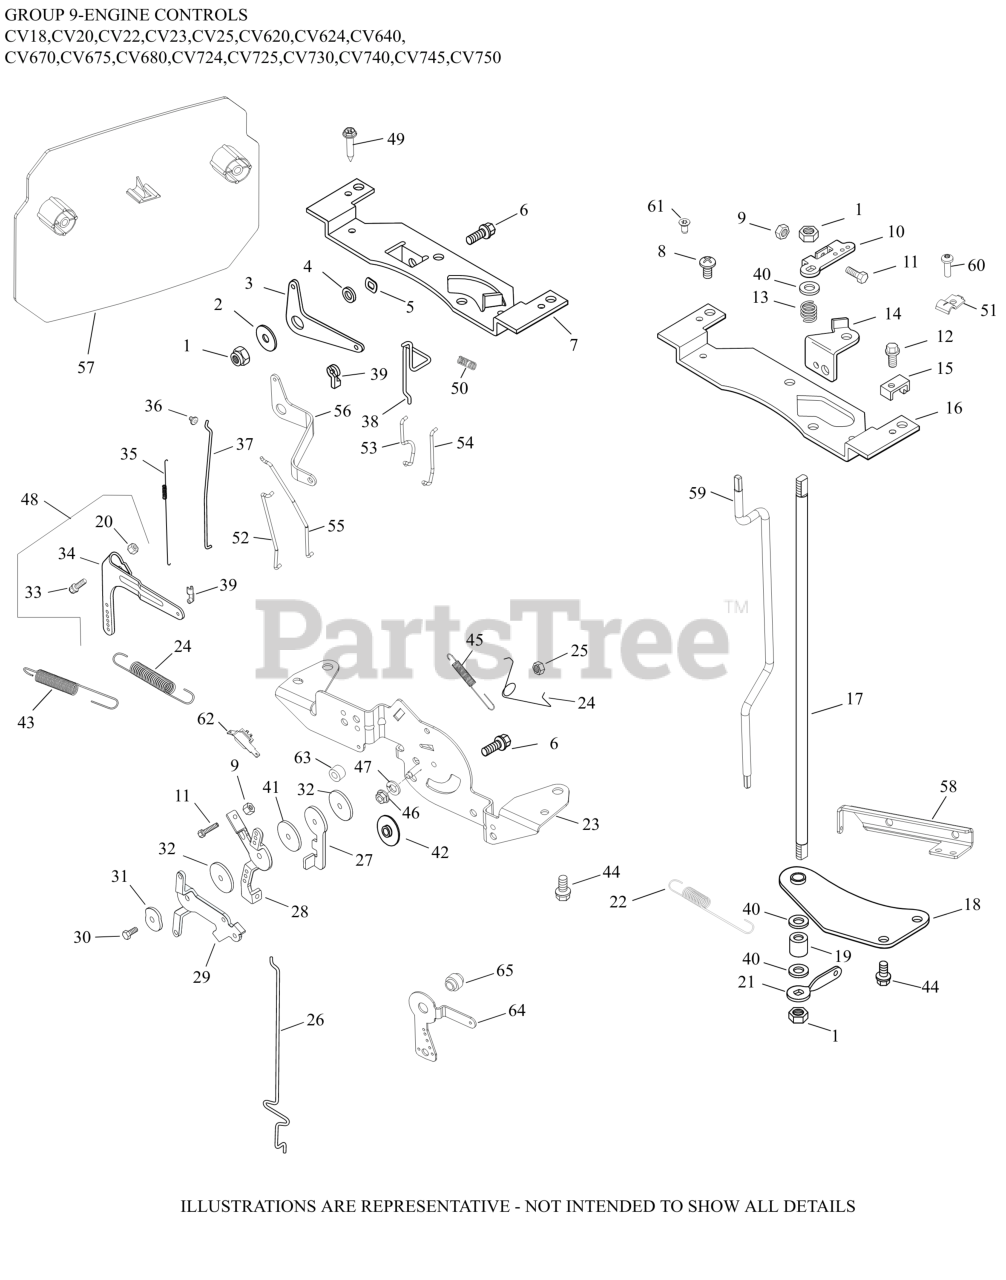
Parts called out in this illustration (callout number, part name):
1	NUT, LOCK M6X1.0
2	WASHER, FLAT 1/4"
3	LEVER, CHOKE
5	WASHER, SPRING 3/8"
6	SCREW, FLG M6X1.0X16
7	BRACKET, CONTROL
9	NUT, M4X0.7
10	LEVER, THROTTLE CONTROL
11	SCREW, CAP M4X.7X30
12	SCREW, HI-LOW
13	SPRING, THROTTLE SHAFT
17	SHAFT, THROTTLE
18	BRACKET, THROTTLE SHAFT
20	NUT, FLG M6X1.0
21	LEVER, THROTTLE CONTROL
22	SPRING, GOVERNOR (BLUE)
33	BOLT, RD HD SQ NECK M6X1.0X25
34	LEVER, GOVERNOR - (#2409069S)
35	SPRING, LINKAGE
36	BUSHING, LINKAGE RETAINING
37	LINKAGE, THROTTLE
38	LINKAGE, CHOKE
39	BUSHING, THROTTLE LINKAGE
40	WASHER, FLAT 1/4"
48	LEVER, GOVERNOR ASSEMBLY
